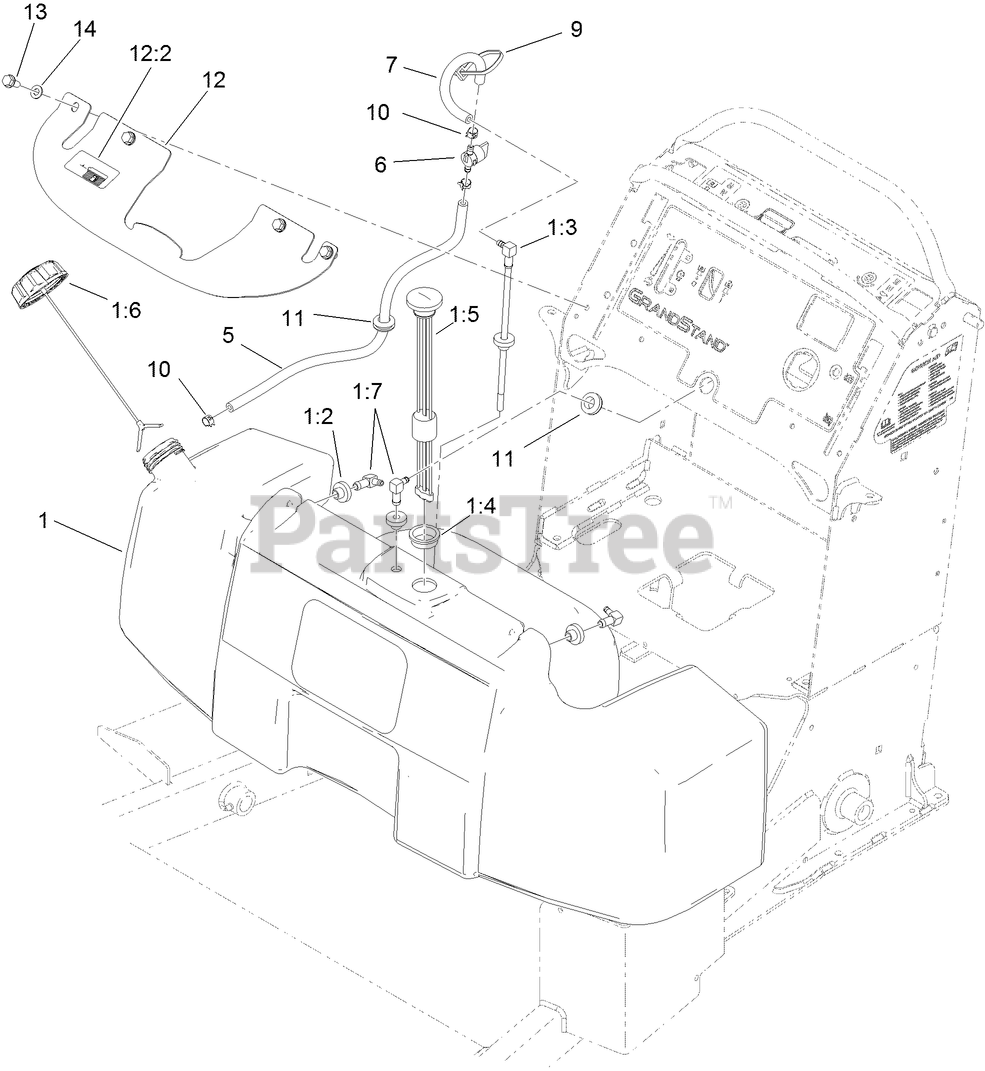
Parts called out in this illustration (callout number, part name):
1	TANK ASM
1:2	BUSHING
1:3	FITTING-FUEL, SCREEN TUBE
1:4	GROMMET
1:5	GUAGE-FUEL
1:6	CAP-FUEL, RATCHETING
1:7	ELBOW-90 DEG
5	HOSE-FUEL
6	VALVE-FUEL
7	HOSE-FUEL
9	TIE-CABLE
10	CLAMP-HOSE
11	GROMMET
12	BRACKET-TANK
12:2	DECAL-FILL, FUEL
13	SCREW-HWHTF
14	WASHER-FLAT
